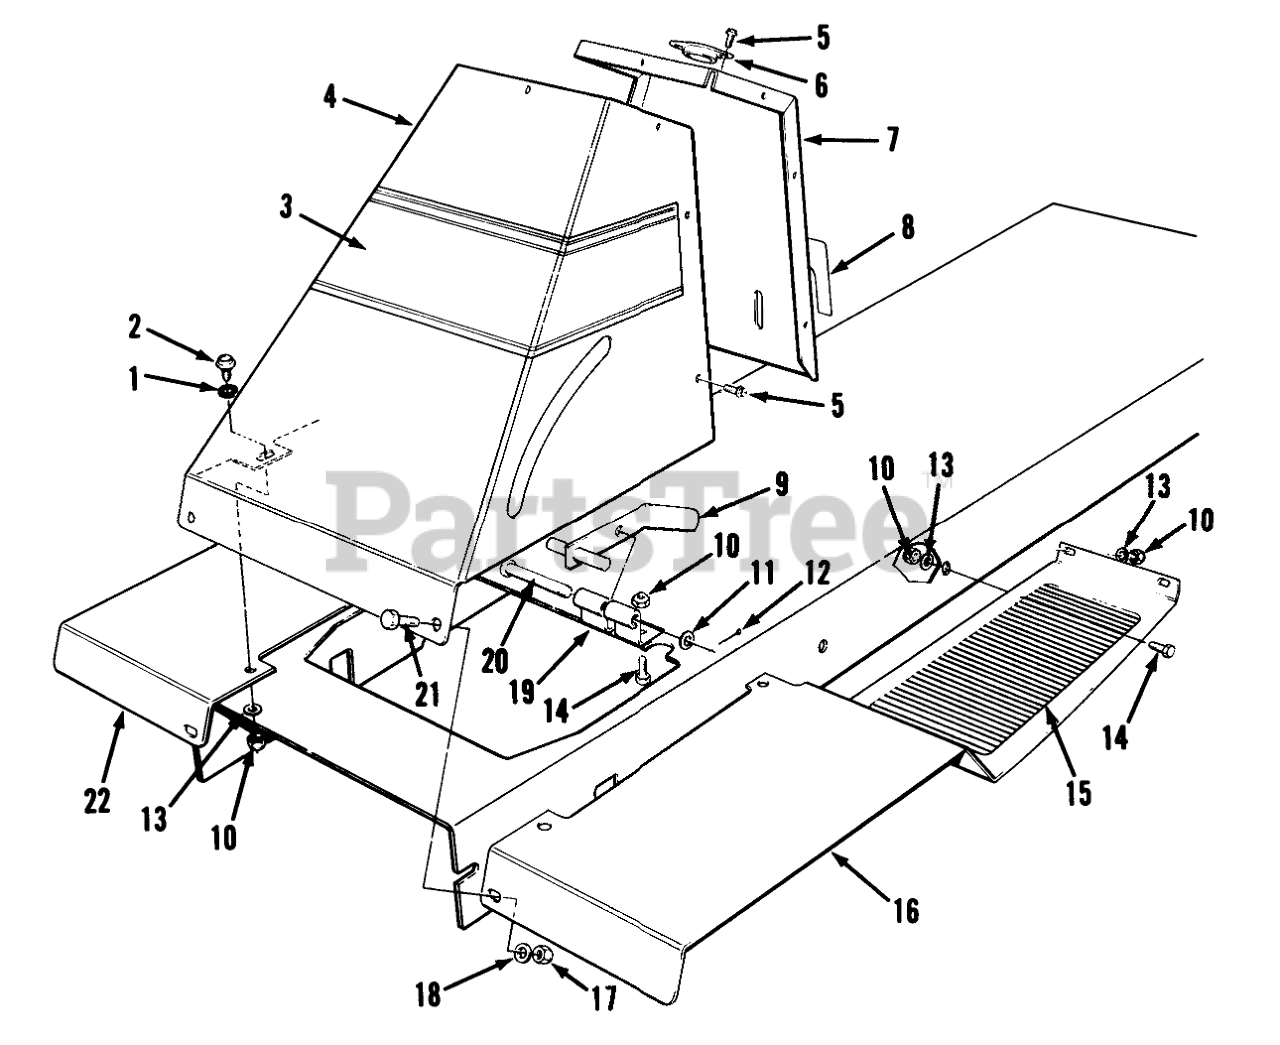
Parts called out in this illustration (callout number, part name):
1	SPACER
2	SCREW-SHOULDER
3	DECAL - STEERING SUPT
4	Tower-Front
5	SCREW-HWHTF
6	GUIDE-STRG SHAFT
7	Tower-Rear
8	PARK BRAKE DECAL
9	PARKING BRAKE WA B
10	NUT-LOCK, NI
11	Washer-Flat 13/32
12	PIN-COTTER
13	Washer
14	SCREW-HH
15	FOOT TREAD L.H.
16	Footrest-LH
17	NUT-LOCK, CONE
18	WASHER-FLAT
19	Bracket-Parking Brake
20	PIN-CLEVIS
21	SCREW-HH
22	Footrest-RH
